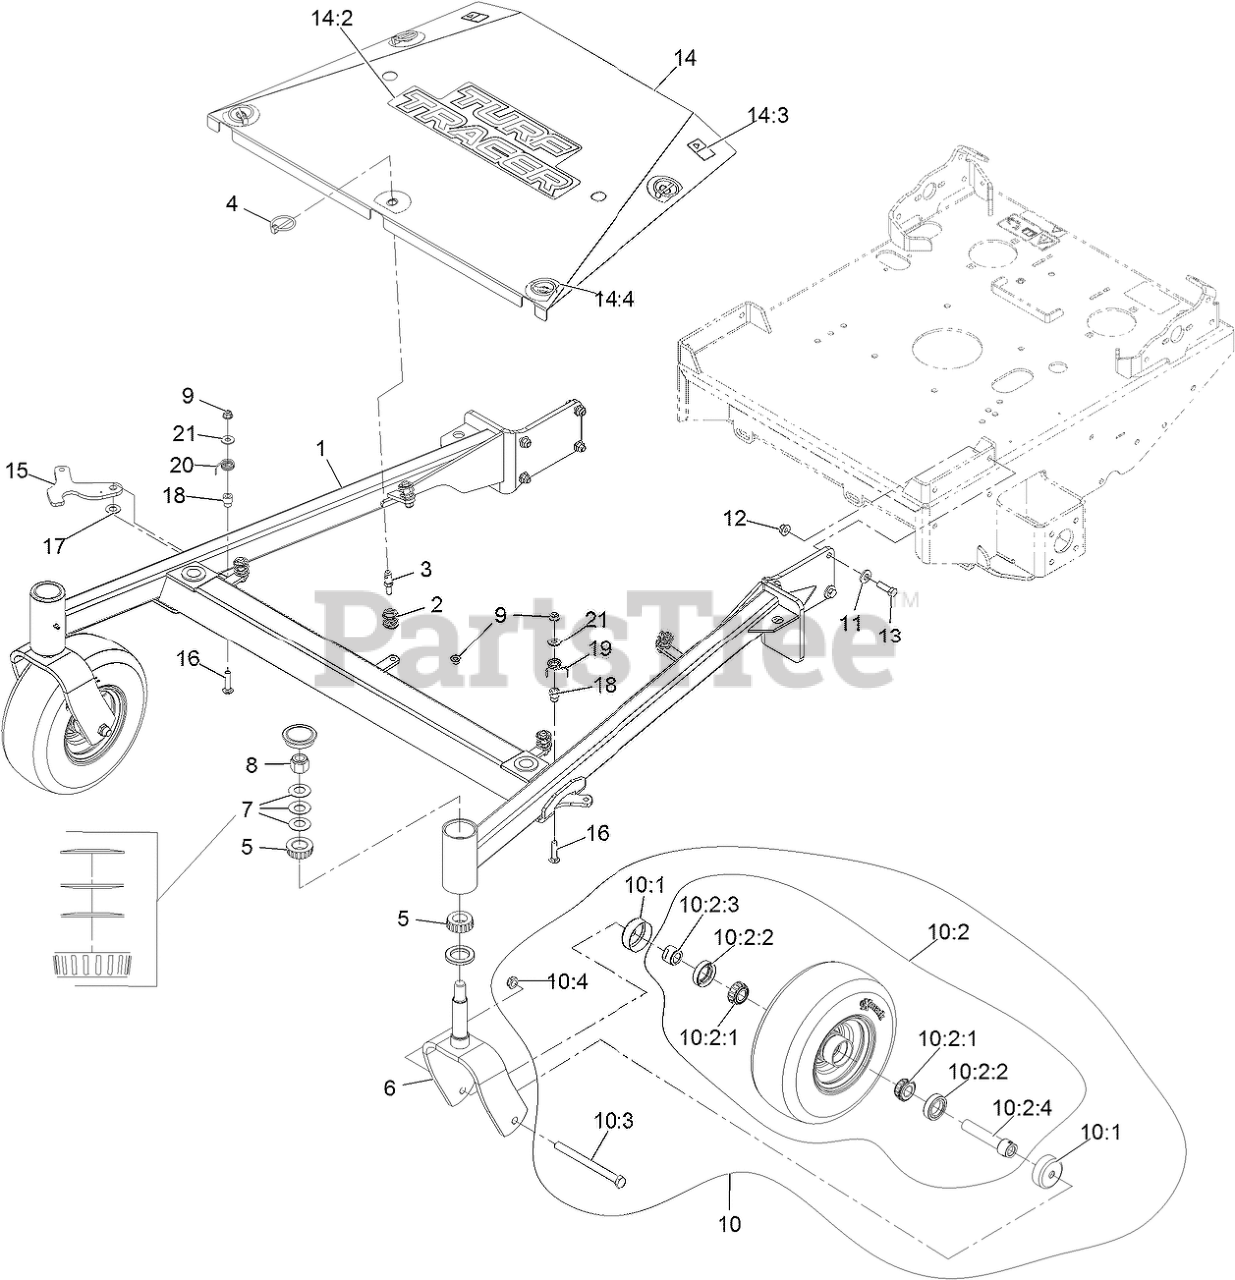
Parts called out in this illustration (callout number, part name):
1	ASM, FRONT FRAME W/ BEARI
3	PIN, SPRING
4	PIN-LYNCH
5	Cone-Bearing Tapered Roller
6	WLD, CASTER FORK
7	WASHER-BELLVILLE
8	NUT-LOCK, NI
9	NUT-HF, NI
10	ASM,WHEEL&BEARINGS
10:1	GUARD-SEAL
10:2	Wheel And Bearing ASM
10:2:1	BEARING-CONE, TAPERED ROLLER
10:2:2	SEAL-CASTER
10:2:3	SPACER-NUT
10:2:4	CASTER AXLE ASM
10:3	SCREW-HH
10:4	NUT-HEX
11	WASHER-BELLEVILLE
12	NUT-HF, NI
13	SCREW-HH
14	ASM, CENTER SHIELD W/ DEC
14:2	DECAL-TURF TRACER
14:3	DECAL-WARNING
14:4	DECAL-SCRATCH COVER
15	LATCH, DECK HEIGHT
16	BOLT-CARR
17	Washer-Plastic
18	Collar-Basket
19	Spring-Torsion, LH (Yellow)
20	Spring-Torsion, RH
21	WASHER-FLAT
